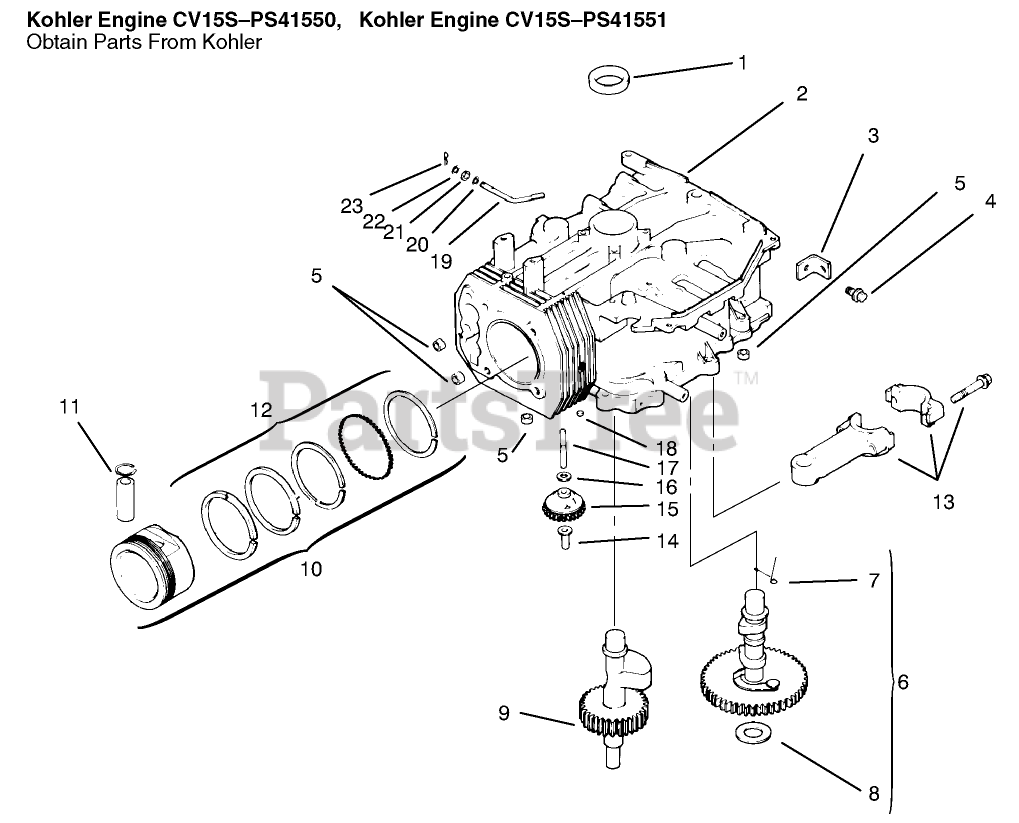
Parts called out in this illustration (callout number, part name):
1	Seal-Crankshaft (Only On: 72042, 72043, 72062, 72063)
2	Block-Short
3	Strap-Lifting (Only On: 72042,72043,72062,72063)
4	Screw M8x1.25x22 (Only On: 72042, 72043, 72062, 72063)
5	Pin-Dowel
6	Kit-Camshaft INC 7-8 (Only On: 72042, 72063, 72062, 72043)
7	Spring-Actuating (Only On: 72042,72043,72062,72063)
8	Shim-Camshaft
9	Shaft-Balance
10	Piston ASM STD Incl 11-2
10	Piston ASM .25 Incl 11-2
10	Piston ASM .50 Incl 11-2
11	Retainer-Piston Pin (Only On: 72042, 72043,72062,72063)
12	Ring Set STD
12	Ring Set .25
12	Ring Set .50
13	Rod Connecting STD
13	Rod Connecting .25
14	Pin-Governor
15	Gear-Governor ASM (Only On: 72042, 72063, 72062, 72043)
17	Shaft-Govenor Gear
19	Kit-Governor Cross
20	Washer, plain 6 mm
21	Seal
22	Washer
23	Clip-Hitch Pin
